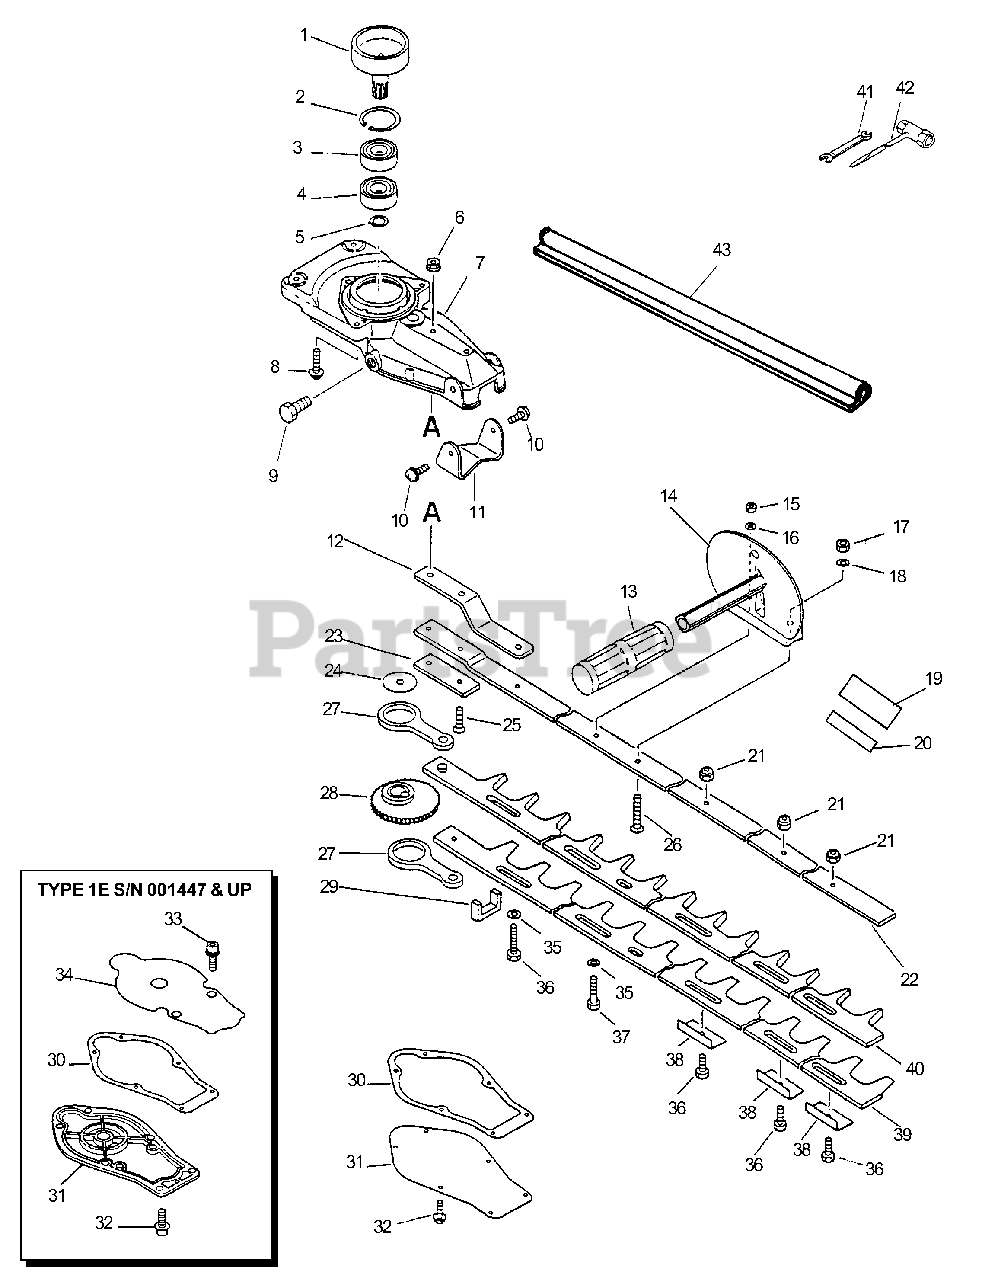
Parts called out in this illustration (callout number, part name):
1	DRUM, CLUTCH
2	RING, RETAINING - 30
3	BEARING, BALL - 6202
4	BEARING, BALL - 6202
5	RING, RETAINING - 14
6	LOCKNUT - 6
7	CASE, GEAR
7	CASE, GEAR - UPPER
8	SCREW - 5X25
9	BOLT - 8X8
10	SCREW - 5X10
11	STAND
12	PLATE, ANGLE
13	GRIP, HANDLE
14	HANDLE - FRONT
17	LOCKNUT - 5
19	LABEL - CAUTION
20	LABEL - CAUTION
22	SUPPORT, BLADE
25	SCREW - 6X25
26	SCREW - 5X30
27	ROD, CONNECTING
28	GEAR - DRIVE
29	SEAL, FELT
30	GASKET, GEAR CASE
31	LID, GEAR CASE
31	LID, GEAR CASE - LOWER
32	SCREW - 4X10
32	SCREW - 4X12
33	SCREW - 5X12
34	LID, GEAR CASE
35	WASHER - 6
36	BOLT - 6X22
38	INSULATOR
39	BLADE - LOWER
40	BLADE - UPPER
41	SPANNER - 8X10mm
42	T-WRENCH - 13X19mm
43	COVER, BLADE
